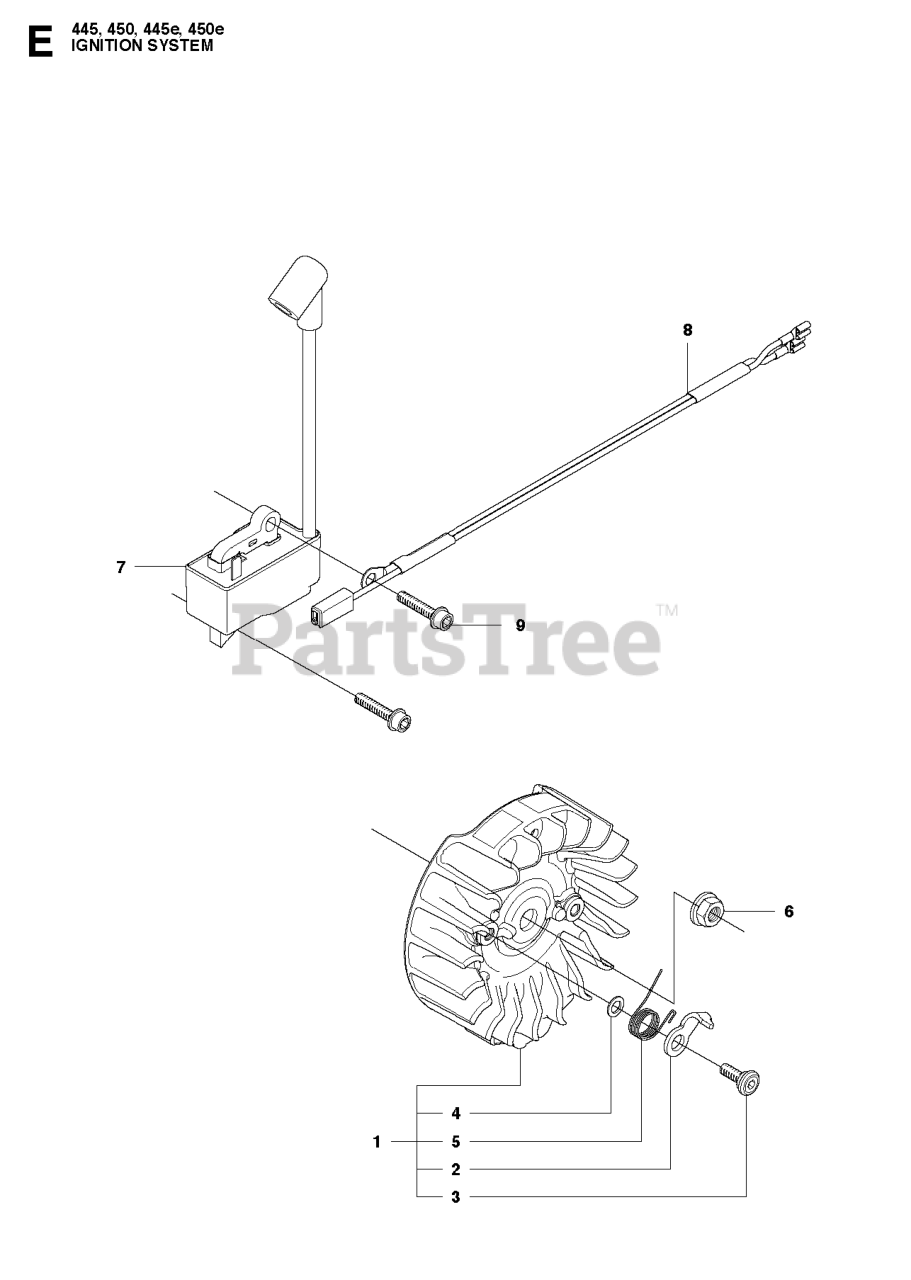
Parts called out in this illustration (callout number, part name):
1	FLYWHEEL ASSY
6	NUT W/ WASHER
7	IGNITION MODULE
8	WIRING ASSY
